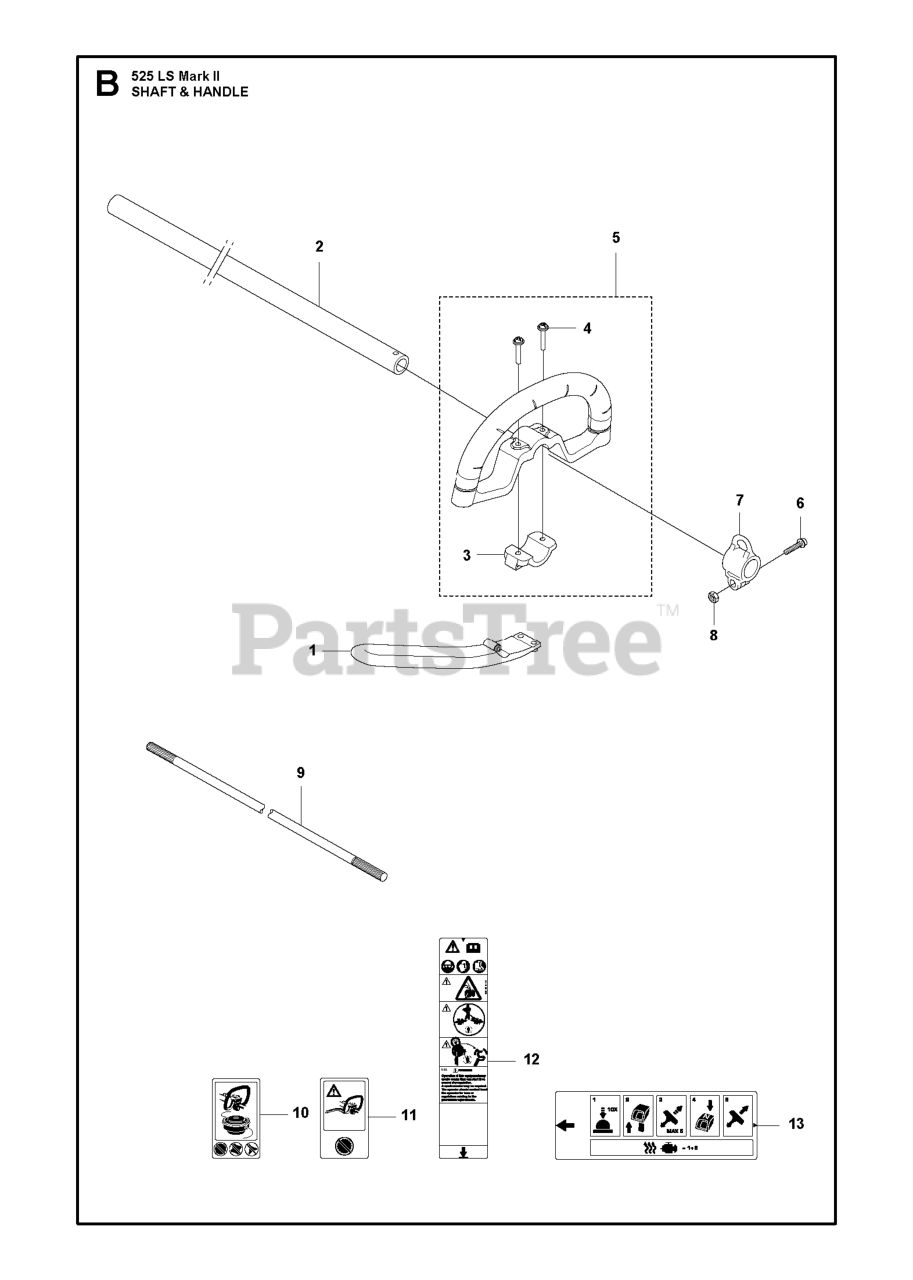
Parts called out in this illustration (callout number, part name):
2	TUBE
5	HANDLE LOOP
7	HARNESS HOLDER
9	DRIVESHAFT
10	DECAL WARNING "NO BLADES"
12	LABEL WARNING TRIMMERS AND BRU
13	DECAL START REMINDER 523/525
